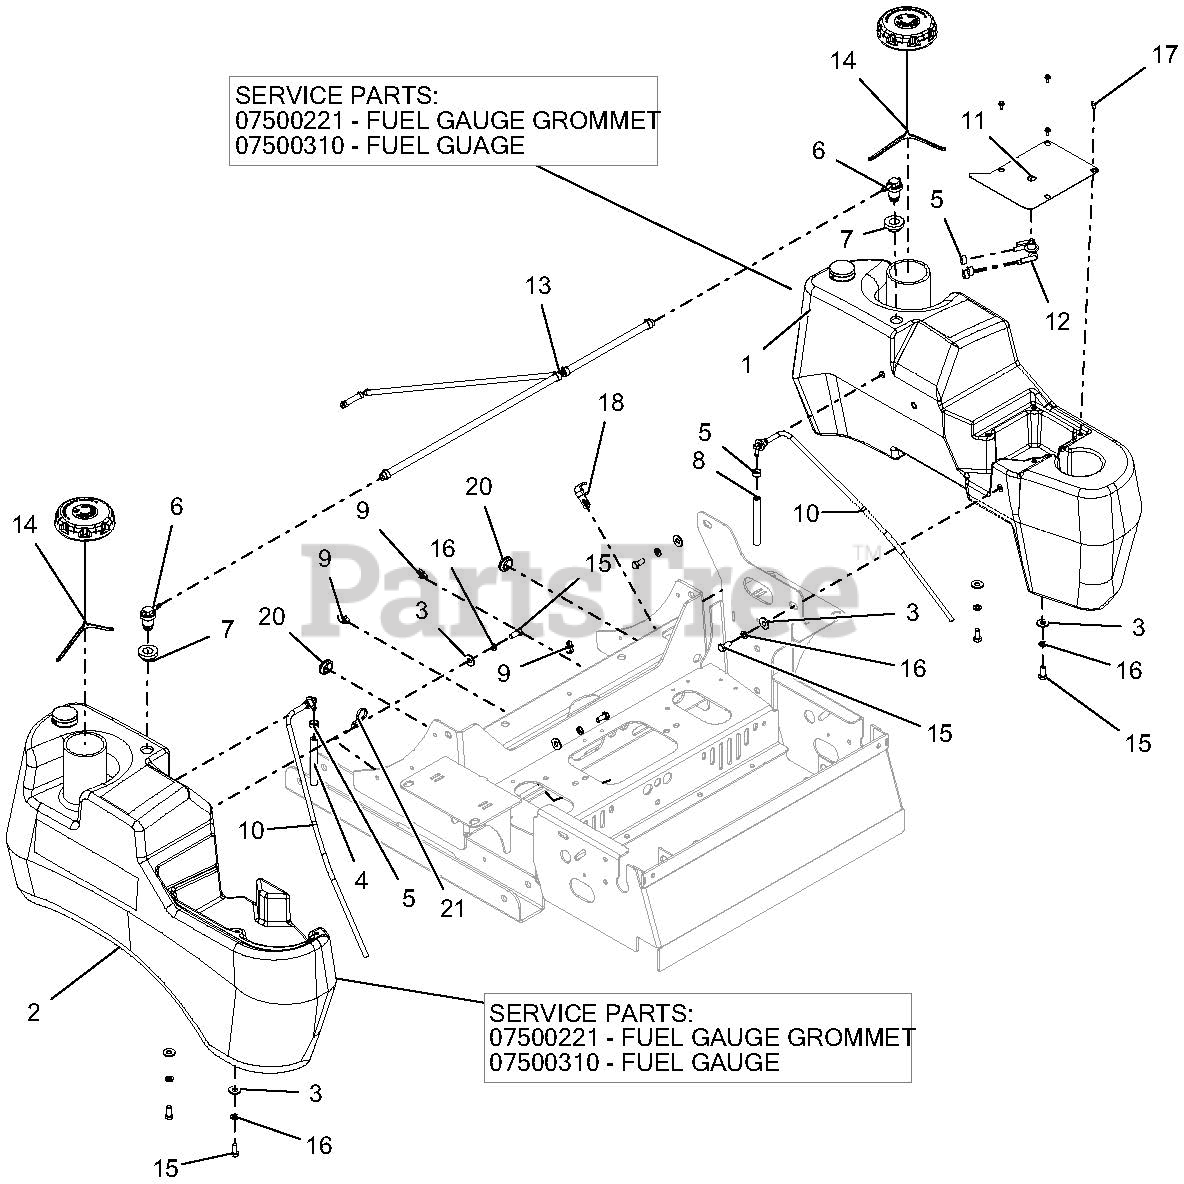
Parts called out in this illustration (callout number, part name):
1	ASSY-LH LARGE FUEL TANK W/MECH GAUGE-GAS
1	FUEL GAUGE GROMMET
1	FUEL GAUGE
2	ASSY-RH LARGE FUEL TANK W/MECH GAUGE-GAS
2	FUEL GAUGE GROMMET
2	FUEL GAUGE
3	WSHR-FL-STL.38X.875X.083 YWZC
4	.25 LOW-PERM GAS HOSE 54.00" LG - RH TANK TO VALVE
5	CLAMP, FUEL LINE
6	VALVE, 2-WAY
7	GROMMET, REMOTE VENT NITRILE
8	.25 LOW-PERM GAS HOSE 19.00" LG - LH TANK TO VALVE
9	CLIP, ROUTING (.50 ID)
10	ASM, LARGE TANK FUEL PICKUP
11	PLATE, FUEL VALVE MOUNTING-RED
12	VALVE, FUEL
13	PT400, FUEL LINE ASSEMBLY
14	CAP, FUEL VENT-IN AUTOLOCK
15	BLT-HEX .31-18X.75 GR5 YWZC
16	WSHR-LK .31X.078 REG YWZC
17	SCR-MCH 10-24X.38 HWHSTAINLESS
18	CLAMP, CUSHIONED STEEL .75
20	GROMMET, RUBBER
21	CABLE TIE W/ TREE (.25 HOLE)
